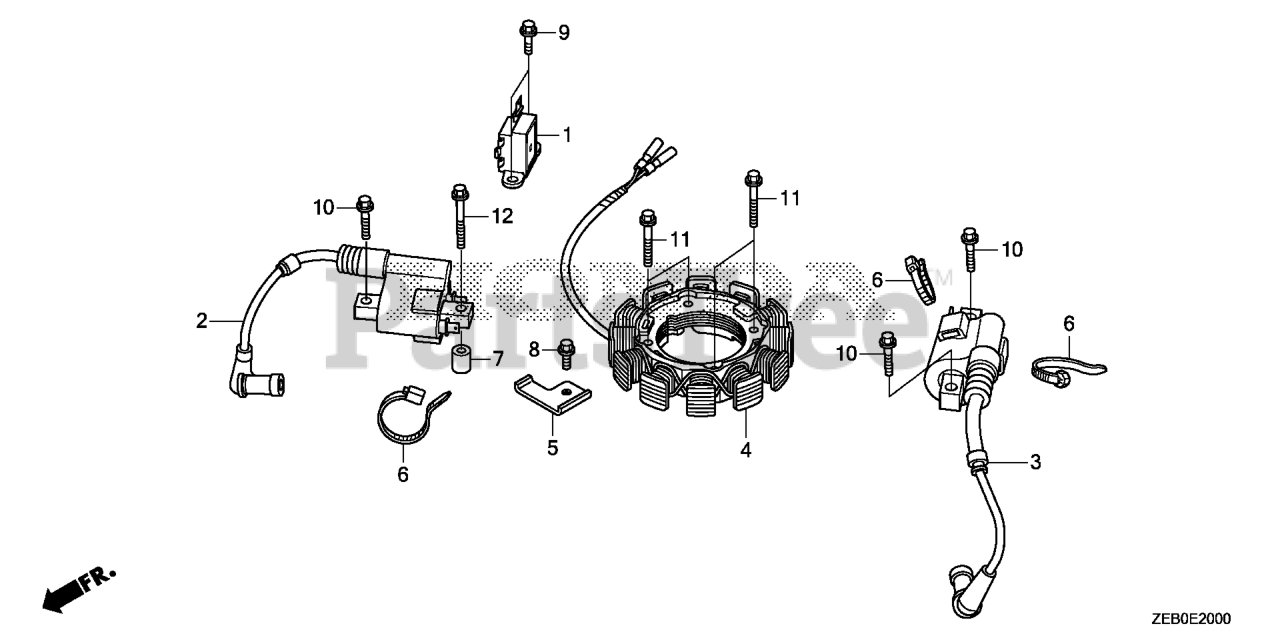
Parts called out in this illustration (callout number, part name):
1	COIL ASSY., PULSER
2	COIL, IGNITION (1)
3	COIL, IGNITION (2)
4	COIL ASSY., CHARGE (17A)
5	BRACKET, HARNESS
6	BAND, WIRE (95MM)
8	BOLT, FLANGE (6X12) Use up to Engine SN 1543277.
9	BOLT, FLANGE (6X14)
10	BOLT, FLANGE (6X25)
11	BOLT, FLANGE (6X32)
12	BOLT, FLANGE (6X25)
